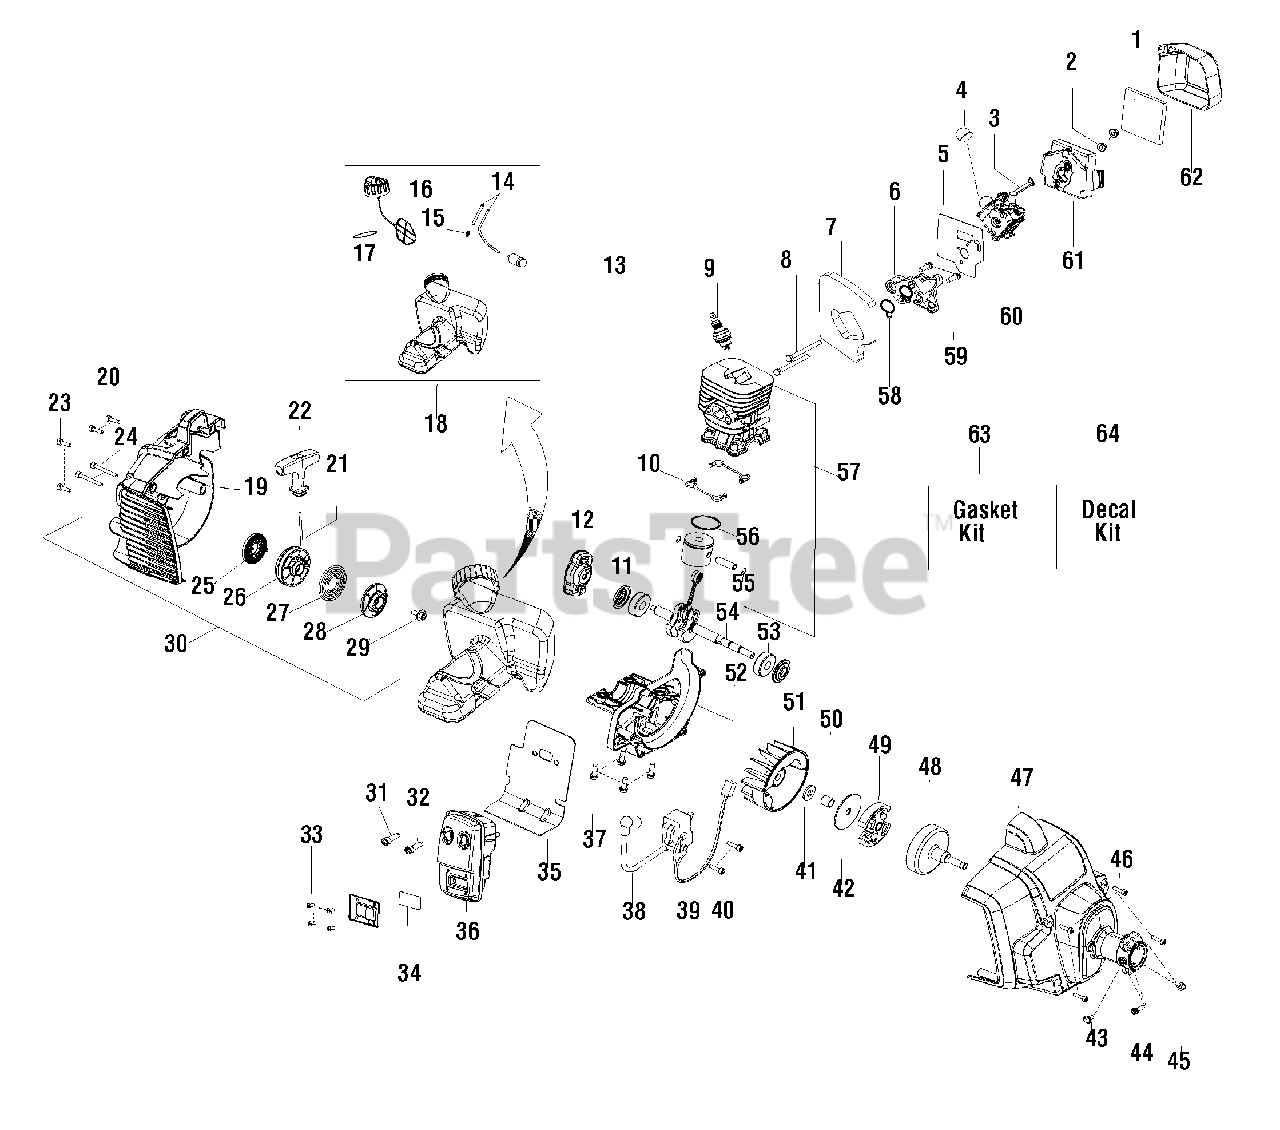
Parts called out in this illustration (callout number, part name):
2	Nut - Carb. Screw
3	Lever - Choke
4	Bulb - Purge
5	Kit - Carb. Gasket
6	Adaptor - Carb.
7	Foam - Gasket
10	Seal - Cylinder
11	Seal - Crankshaft
12	Assy - Starter Pawl
13	Assy - Fuel Filter
14	Kit - Fuel Line
15	Fitting - Fuel line
16	Assy - Cap w/ret.
17	O-ring
18	Kit - Fuel Tank Assy.
19	Housing - Starter
20	Screw
21	Kit - Rope
22	Handle - Starter
23	Screw
24	Screw
25	Kit - Spring
26	Kit - Starter Pulley
27	Spring - Driver
28	Pulley - Driver
30	Kit - Starter Housing
34	Kit - Spark
35	Gasket
36	Kit - Muffler
39	Assy - Leadwire
42	Washer - Clutch
47	Assy - Fan Housing
48	Assy - Clutch Drum
49	Assy - Clutch
50	Spacer
51	Flywheel
52	Crankcase - Cast
53	Bearing
54	Assy - Crankshaft
55	Retainer - Piston Pin
56	Ring - Piston
57	Kit - Piston/Cyl.
58	Seal
60	Kit - Carb.
61	Housing, Filter
62	Cover - Filter Housing
63	Kit - Gasket
64	Kit - Decal
